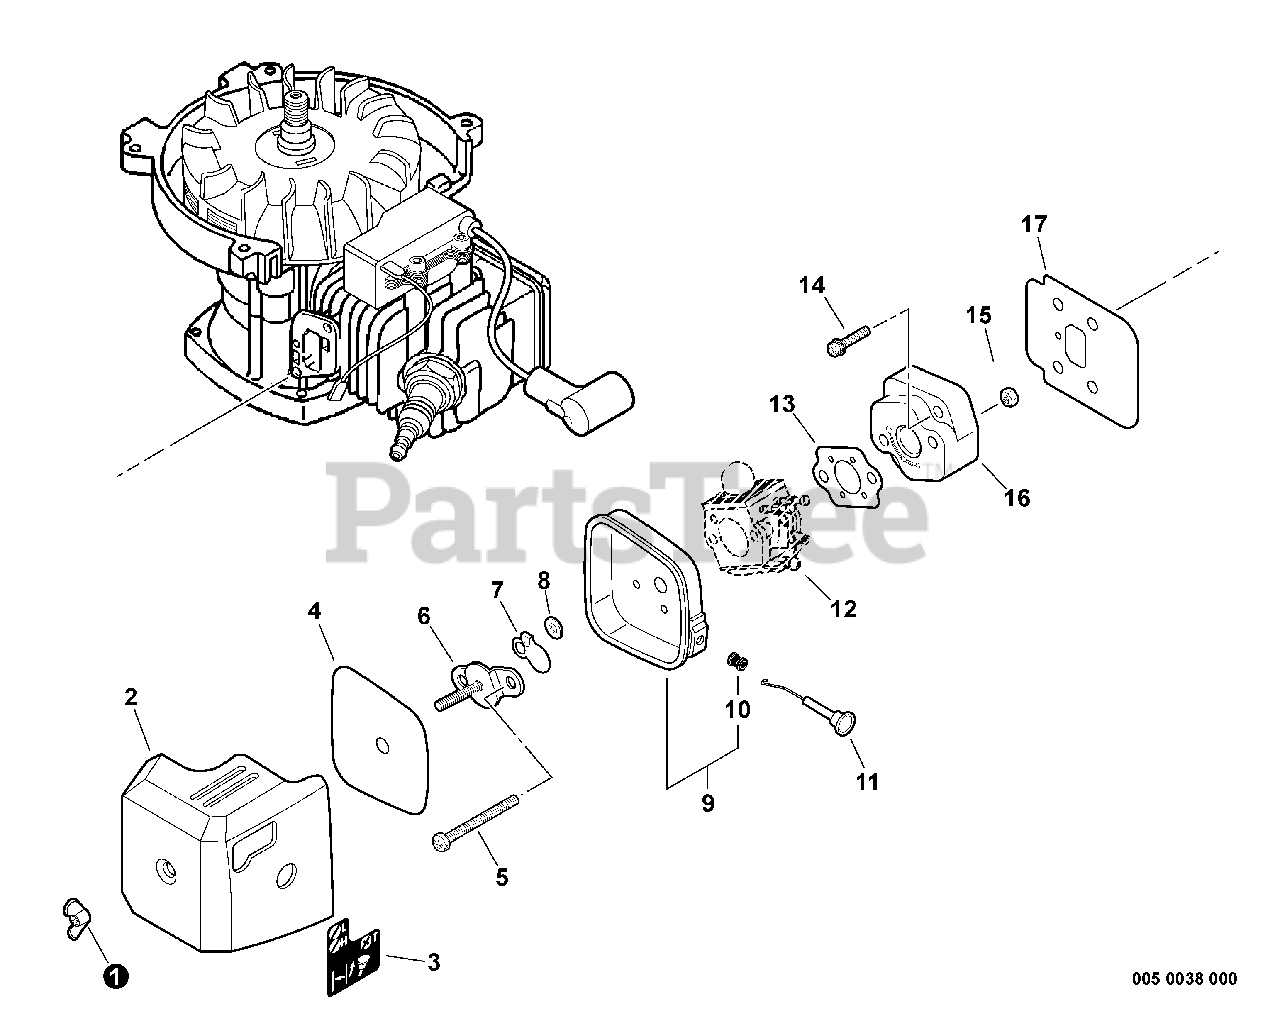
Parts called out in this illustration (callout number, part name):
1	WINGNUT - 6
2	COVER, AIR FILTER
3	LABEL, CHOKE
4	FILTER, AIR
5	SCREW 5×57
6	PLATE, PREVENT
7	SHUTTER, CHOKE
8	WASHER 5.2×8×0.8T
9	CASE, AIR FILTER
10	GROMMET, CHOKE
11	ROD, CHOKE
12	CARBURETOR
13	GASKET, INTAKE
14	SCREW 5×20
15	NUT M5
16	INSULATOR, INTAKE
17	HEAT SHIELD, INTAKE
